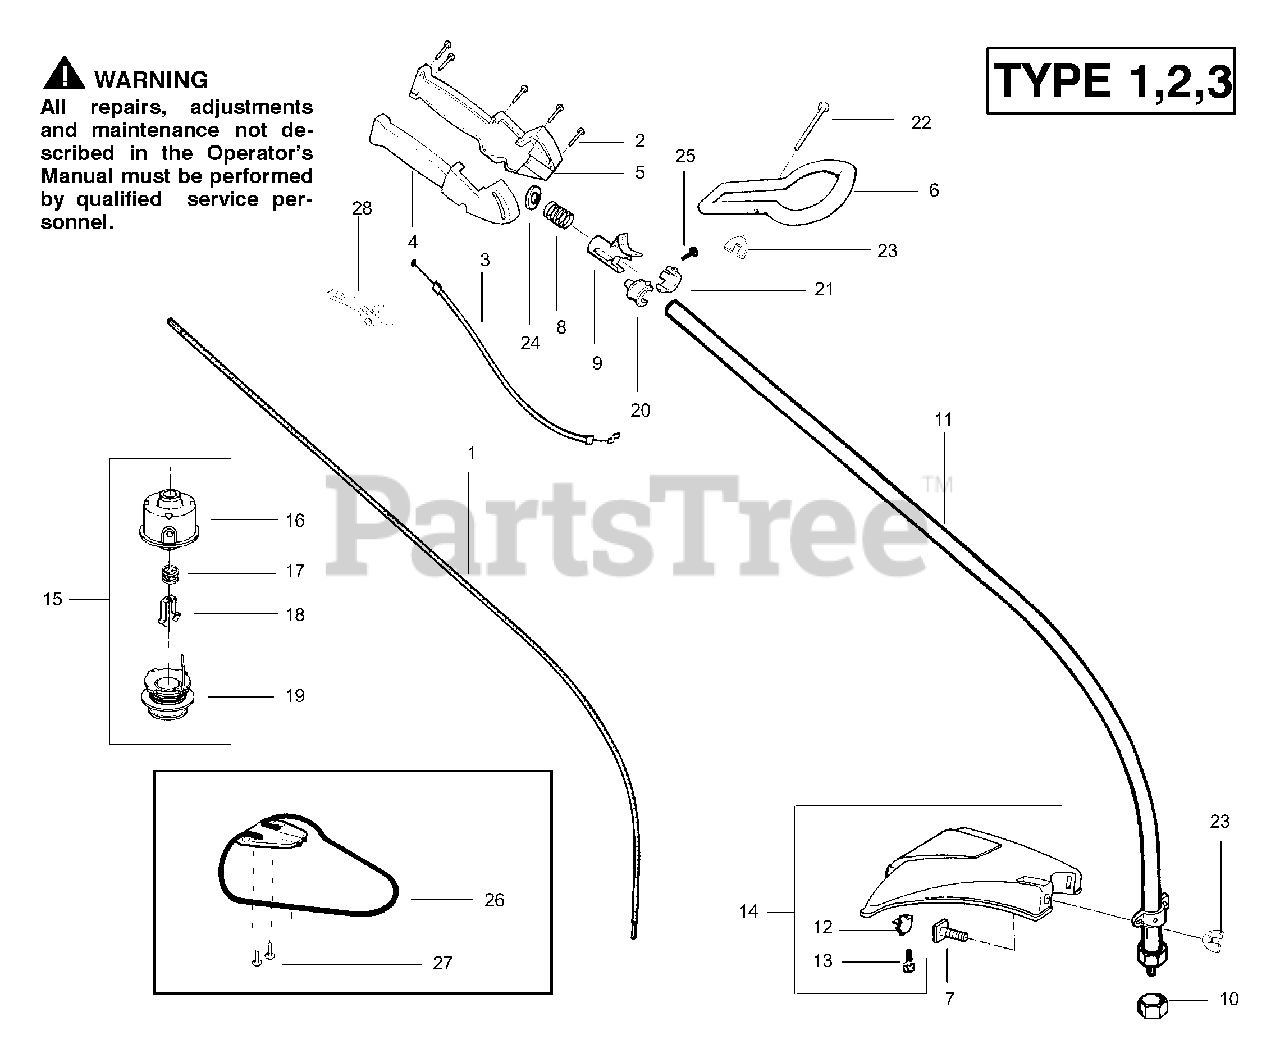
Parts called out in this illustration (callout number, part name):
1	Drive Shaft-Flex (Type 1)
1	Drive Shaft-Flex (Type 2,3)
3	Assy-Throttle Cable (Type 1)
3	Assy-Throttle Cable (Type 2,3)
4	Throttle Hsg. (Right)
5	Throttle Hsg. (Left)
6	Assist Handle
7	Bolt-Shield
8	Spring-Compression
9	Actuator
10	Dust Cup (Type 1)
10	Dust Cup (Type 2,3)
11	Drive Shaft Hsg. Ass'y
11	(Type 1)
11	(Type 2,3)
12	Line Limiter
13	Screw-Line Limiter
14	Shield Kit Ass'y.
15	Cutting Head Ass'y.
16	Hub Ass'y
17	Spring-Return
18	Retainer-Spool
19	Spool w/Line
20	Locator-left
21	Locator-right
22	Bolt-Handle
23	Nut-Wing
25	Screw
26	Assy. wire form
